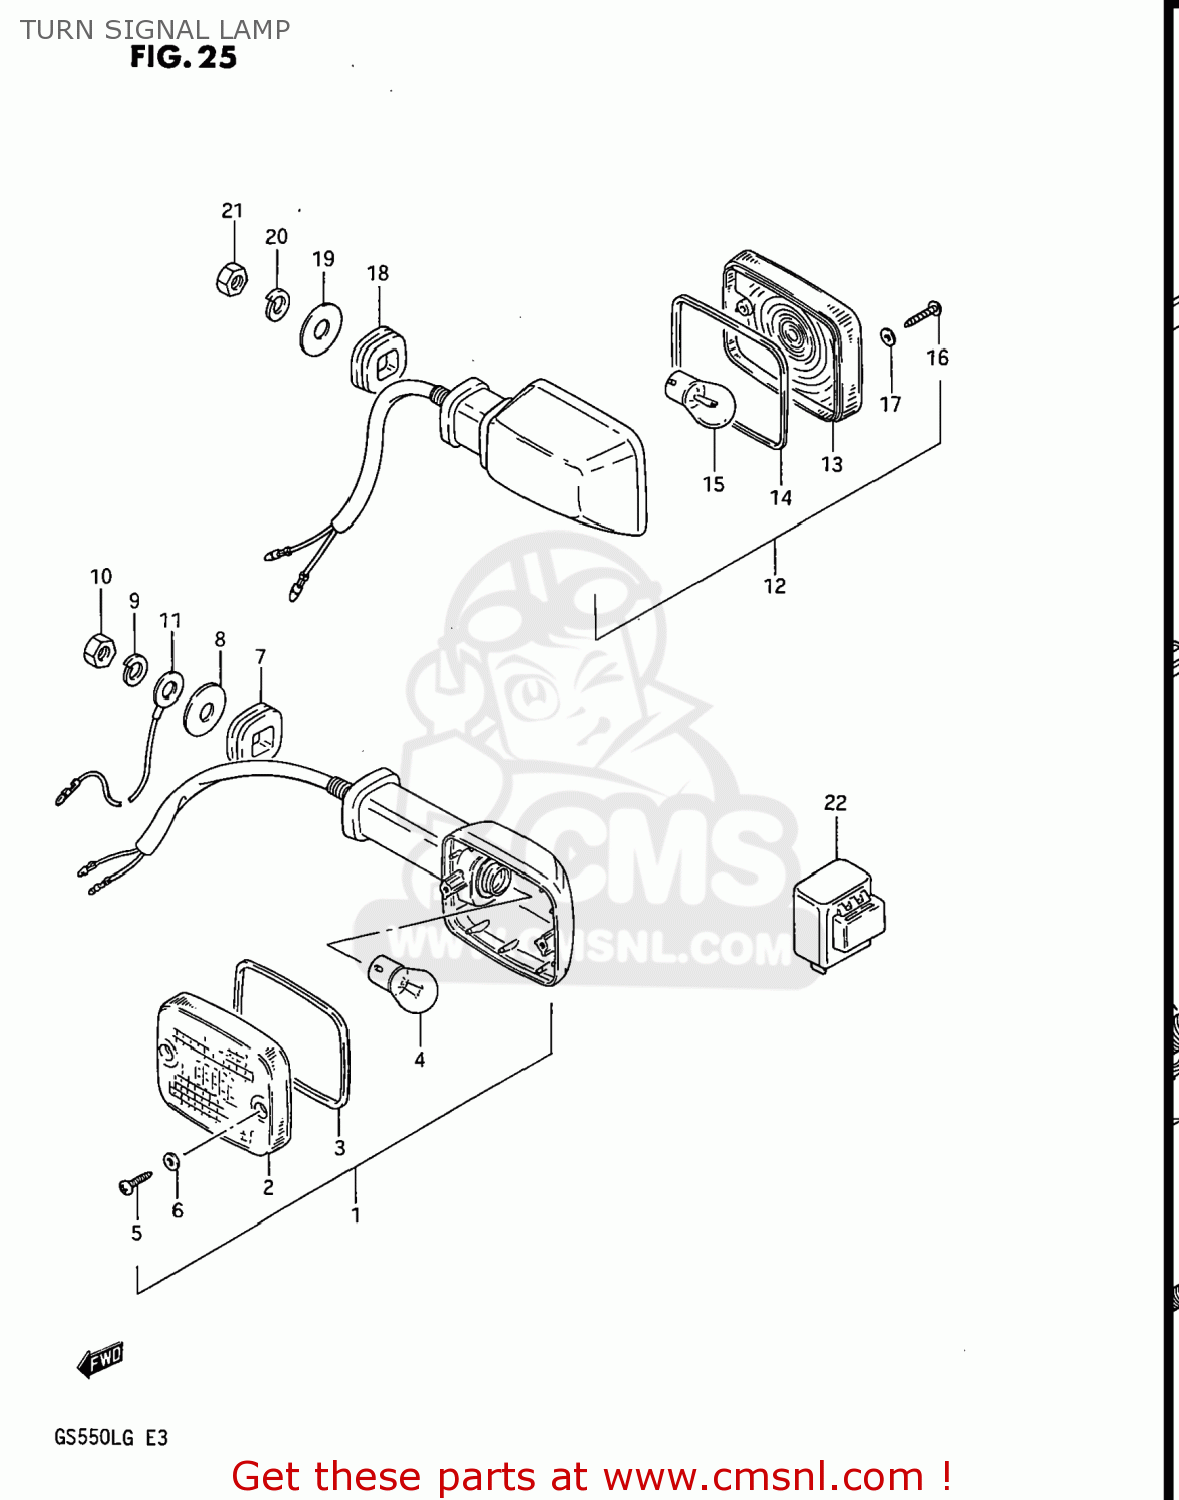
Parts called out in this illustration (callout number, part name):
1	LAMP ASSY,FR TURN SIGNAL
2	LENS
3	GASKET (NAS)
4	BULB(12V23W)
5	SCREW
6	GASKET (NAS)
7	CUSHION
8	WASHER (10.5X30X2.3)
9	LOCK WASHER
10	NUT
11	WIRE
12	LAMP ASSY,RR TURNSIGNAL
13	LENS
14	GASKET (NAS)
15	BULB(12V23W,STANLEY,A4577A)
16	SCREW
17	GASKET (NAS)
18	CUSHION
19	WASHER (10.5X30X2.3)
20	LOCK WASHER
21	NUT
22	RELAY ASSEMBLY,TURN SIGNAL
